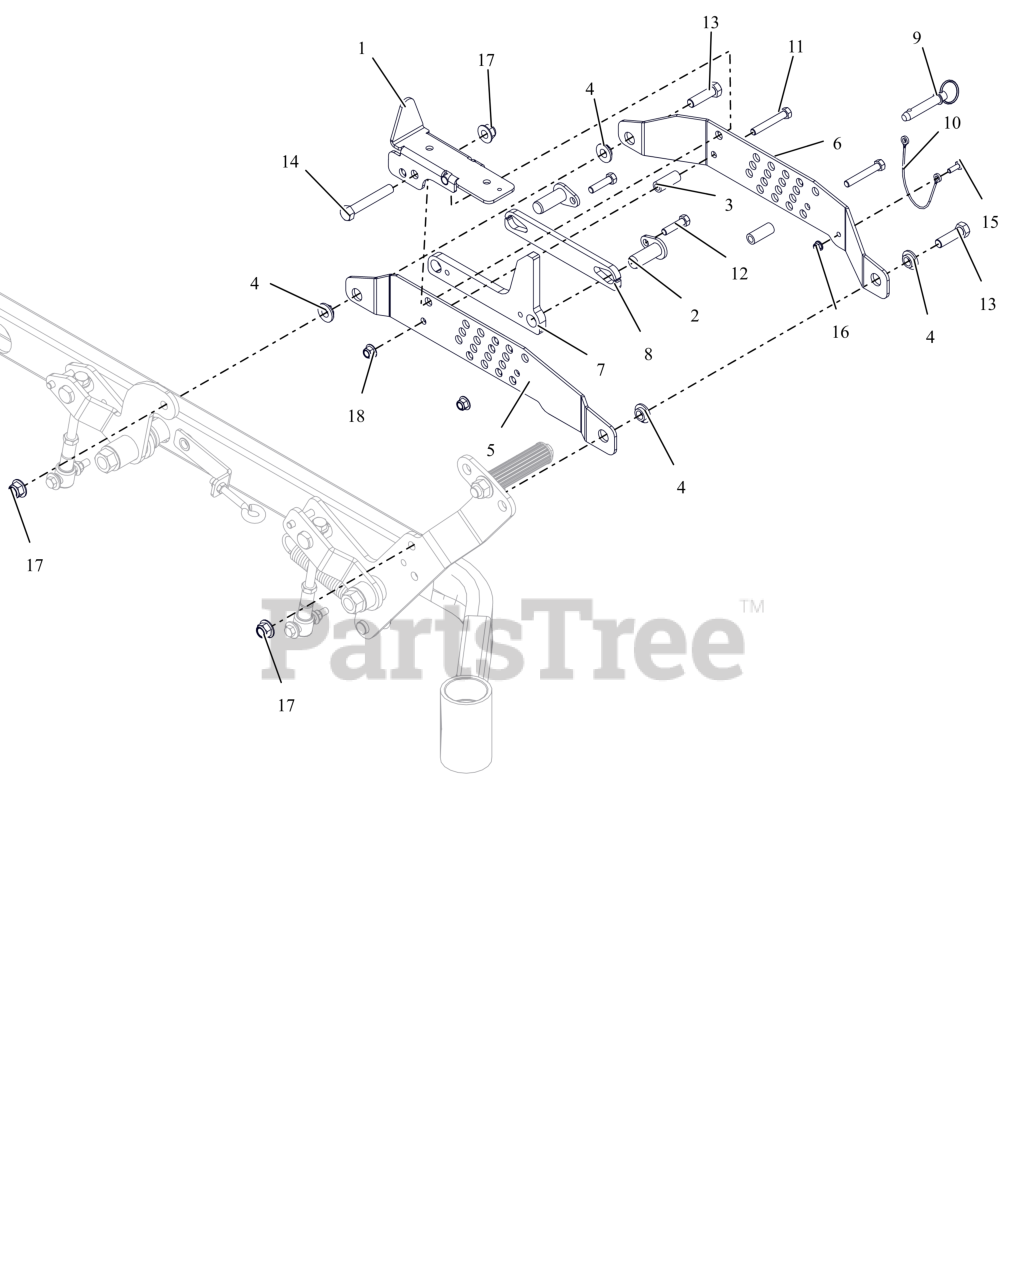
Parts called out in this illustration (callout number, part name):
1	MECHANICAL LOCK-UP WMT - BLACK
2	WLDMT, PIN HOC MOUNTING
3	SPACER, .375 X .625 X 1.54
4	BSHG-FLG .515X.750X.310X1.120
5	RH OTBRRD LIFT/CUT HT BRKT-BLK
6	RH INBRD LIFT/CUT HT BRKT- BLK
7	HOC STOP BRKT - BLK
8	HOC STOP SPACER - BLK
9	PIN, .50 X 2.00 USABLE LG BALL
10	CABLE, 12.0 LANYARD, NYLON
11	BLT, HEX .38-16X2.50 G5 ZCC
12	BLT, HEX 0.375-16X1.5 GR5 ZCC EP30
13	BLT, HEX .50-13X1.75 G5 ZCC
14	BLT,HEX .50-13X3.25 G5 ZCC
15	BLT, HEX .25-20X.75 G5 ZCC
16	NUT,NYL-FLG .25-20 GF ZCC
17	NUT,NYL-FLG .50-13 GF ZCC
18	NUT,NYL-FLG .38-16 GF ZCC
